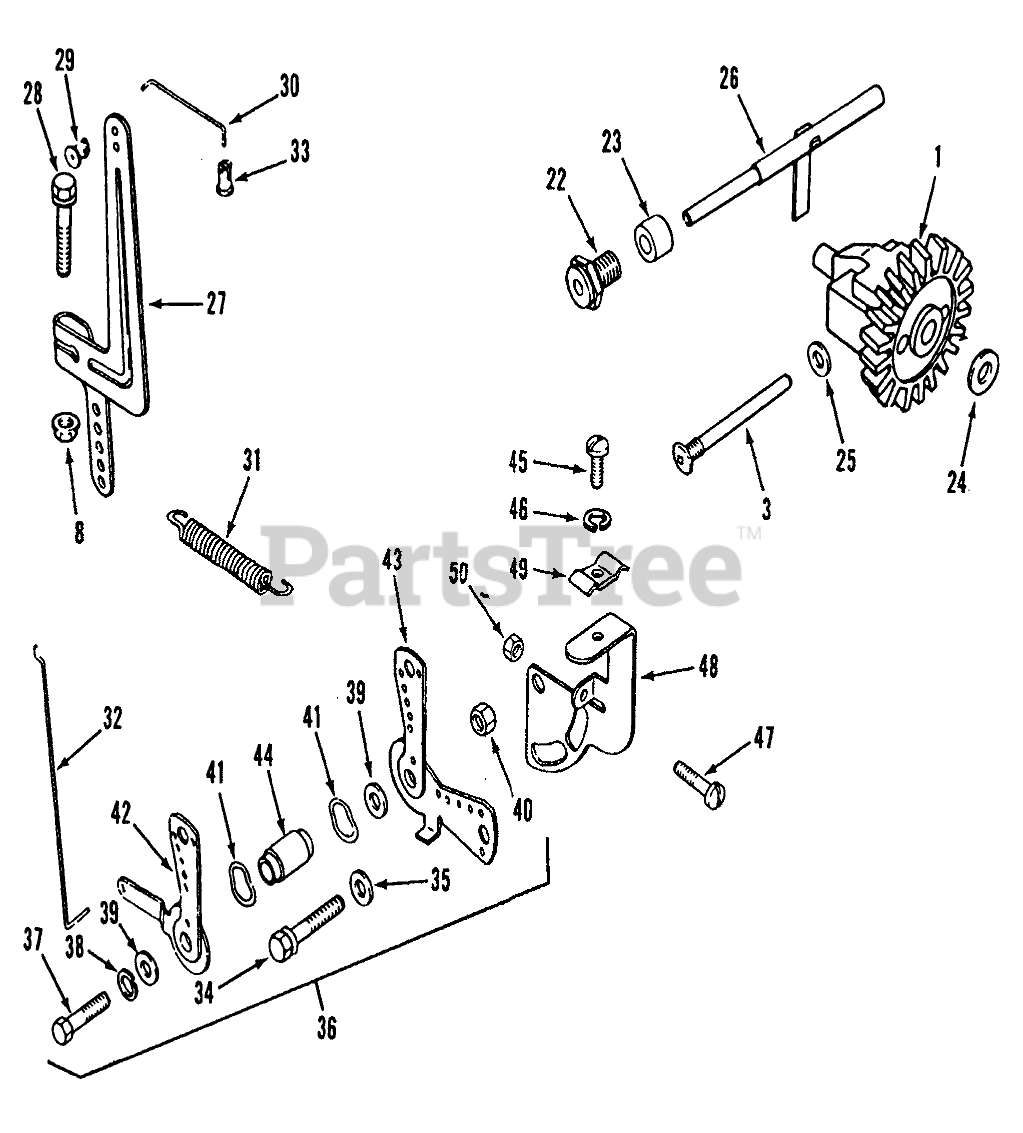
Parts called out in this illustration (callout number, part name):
1	Governor Gear Kit (Includes 24)
3	Pin-GovemorStop
8	Palnut
22	Bushing
23	Spacer
24	Washer
25	Washer-Plain
26	Kit-Governor Shaft
27	Lever-Governor
28	Screw
29	White Bushing
30	Unkage-Governor
31	Spring-Governor
32	Linkage-Choke
33	Yellow Bushing
34	H.C. Sems Screw 1/4-20 x 1/2
35	Washer
36	Choke Lever Assembly (Includes Items 37 thru 44)
37	Screw
38	Washer
39	Washer
40	Nut
41	Washer
42	Choke Control Lever
43	Throttle Control Lever
44	Spacer
45	Screw-F.H.M.
46	Washer-Lock
47	Screw
48	Bracket
49	Clamp
50	Nut
